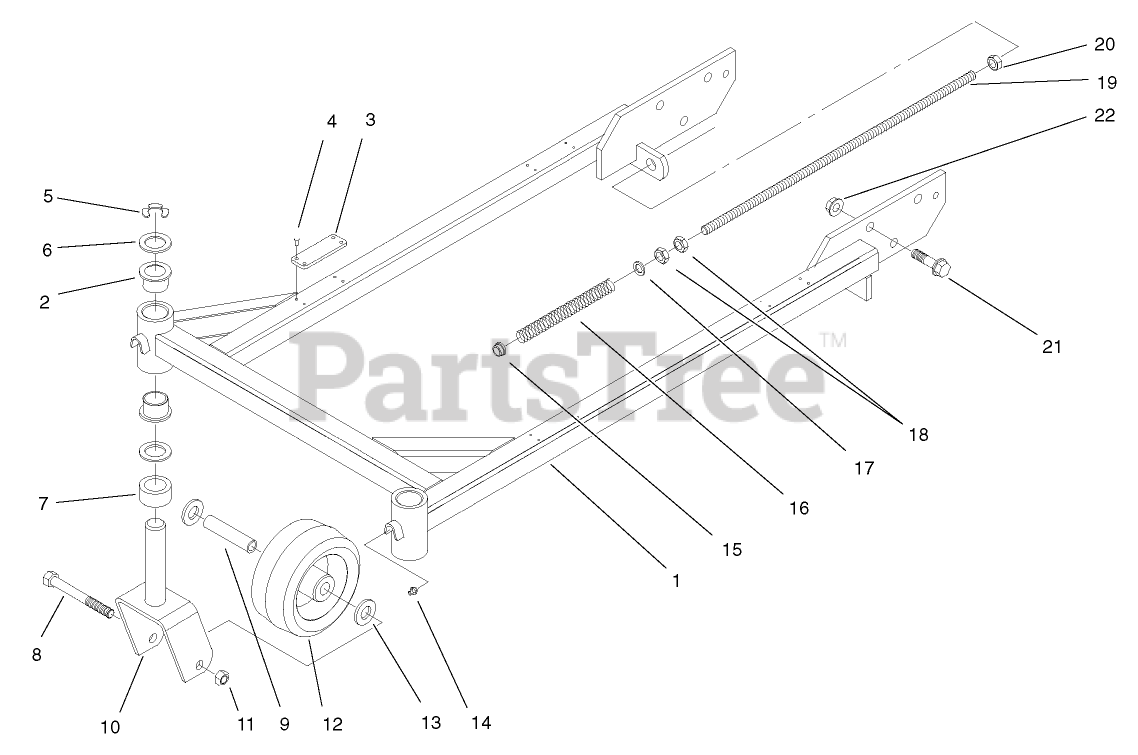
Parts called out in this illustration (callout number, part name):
1	Frame-Carrier
2	BUSHING
3	PAD-RUBBER
4	RIVET
5	RING-RETAINING
6	WASHER-THRUST
7	SPACER-CASTOR
8	SCREW-HH
9	SPANNER
10	FORK-CASTER ASM
11	NUT-HEX
12	CASTER WHEEL ASM
13	SPACER-WHEEL
14	FITTING-GREASE
15	BUSHING-FLANGE
16	SPRING
17	WASHER
18	NUT-JAM
19	SHAFT-ADJUSTING
20	NUT-LOCK, NI
21	SCREW-HHF
22	NUT-HF
